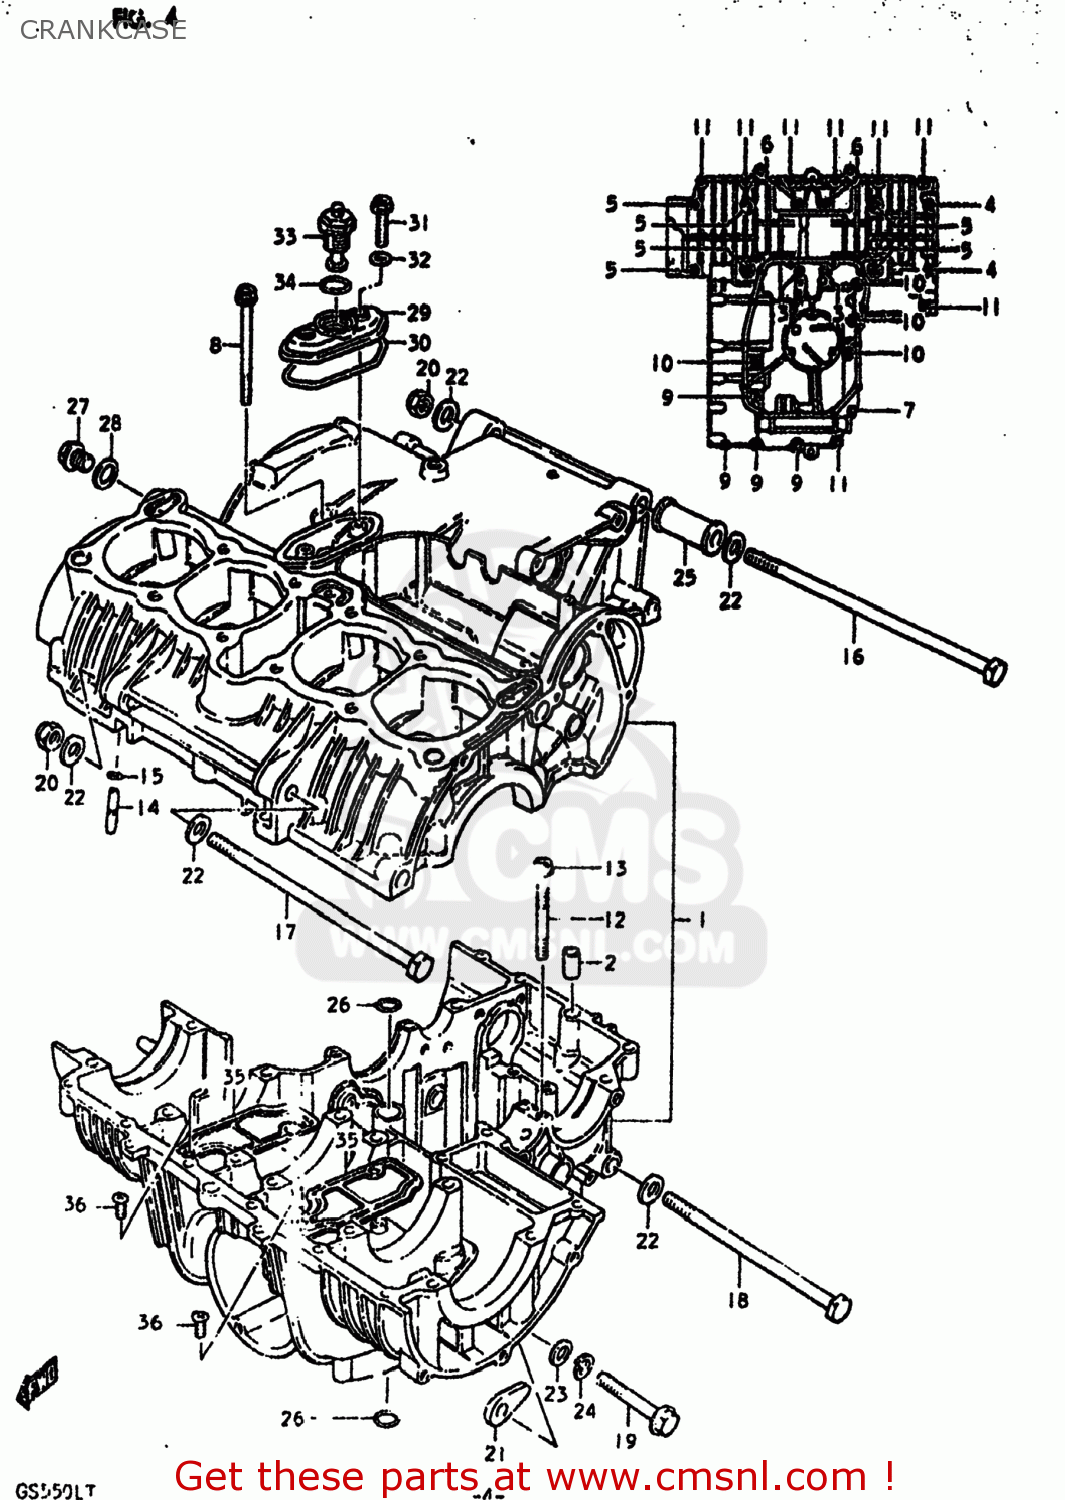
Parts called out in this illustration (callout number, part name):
1	CRANKCASE SET
2	PIN
3	BOLT
4	BOLT 8X90
5	BOLT (8X70)
6	BOLT 8X55
7	BOLT (8X45)
8	BOLT (6X90)
9	BOLT (6X60)
10	BOLT ,6X50
11	BOLT
12	STUD BOLT
13	NUT
14	UNION
15	O-RING
16	BOLT 10X270
17	BOLT
18	BOLT(10X165)
19	BOLT 10X55
20	NUT
21	NUT
22	WASHER
23	WASHER(10.5X20X3.2)
24	LOCK WASHER
25	SPACER,ENGINE MOUNT
26	O RING(D:3.2,ID:12.9)
27	PLUG (14X12)
28	GASKET(14X19.2X2) (NAS)
29	HOUSING,OIL PRESSURE SWITCH
30	O RING,PRESSURE SWITCH HOUSING
31	BOLT
32	GASKET (NAS)
33	SWITCH ASSEMBLY
34	O RING(D:1.9,ID:18.8)
35	PLATE,OIL SEPARATOR
36	SCREW
